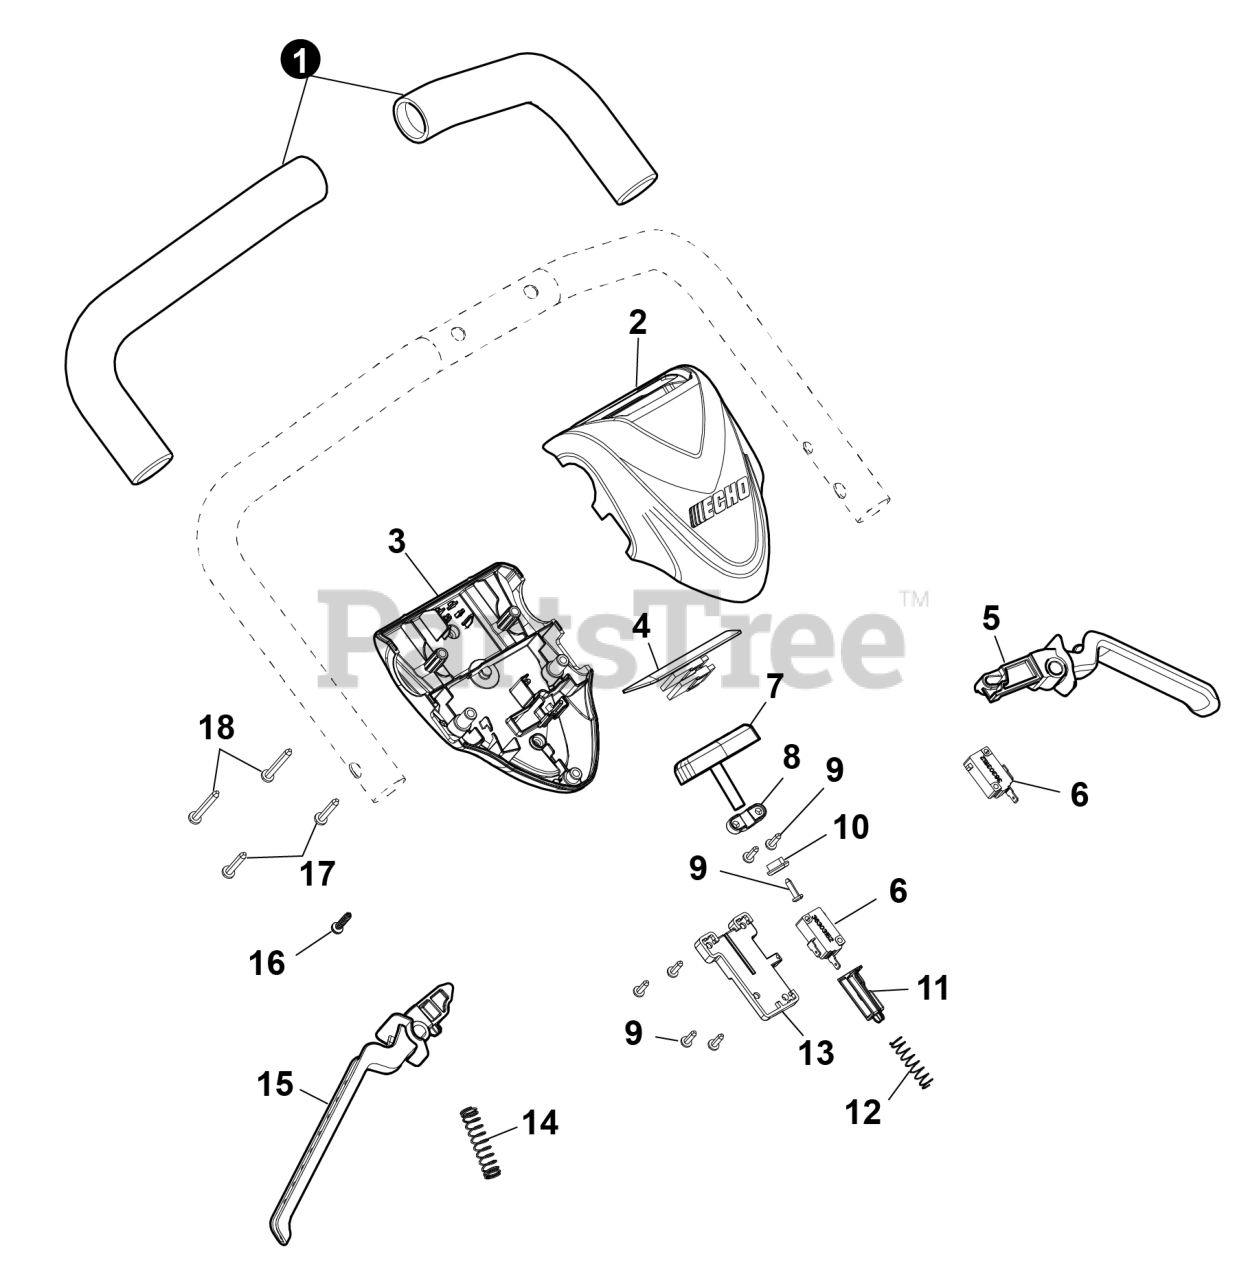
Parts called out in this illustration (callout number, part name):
1	GRIP, HANDLE
2	COVER, TOP SWITCHBOX
3	COVER,LOWER SWITCHBOX
4	SWITCH,MEMBRANE
5	TRIGGER, LEFT
7	BUTTON, SWITCH
8	PLATE, RETAINING
13	PLATE, RETAINING
15	TRIGGER, RIGHT
